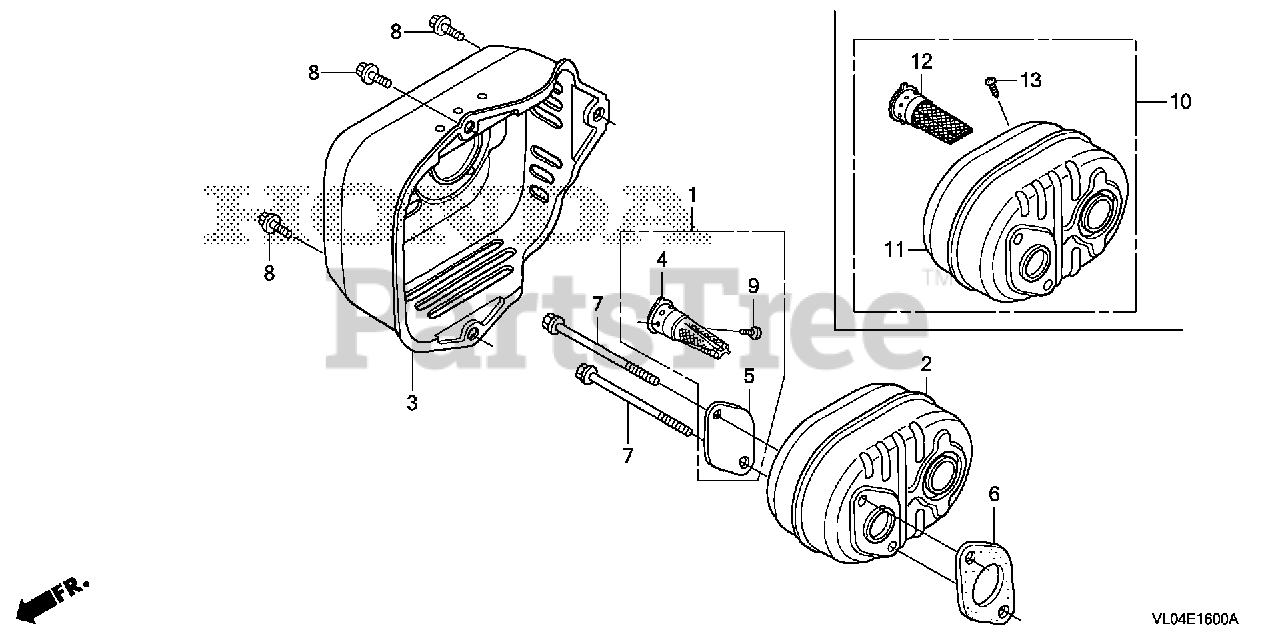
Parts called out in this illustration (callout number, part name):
3	PROTECTOR, MUFFLER
6	GASKET, MUFFLER
7	BOLT, FLANGE (6X79) (CT200)
8	BOLT, FLANGE (6X12) (CT200)
10	MUFFLER ASSY. (ARRESTER)
11	MUFFLER
12	ARRESTER, SPARK
13	SCREW, TAPPING (4X6) (TO INSTALL OPTIONAL SPARK ARRESTER)
